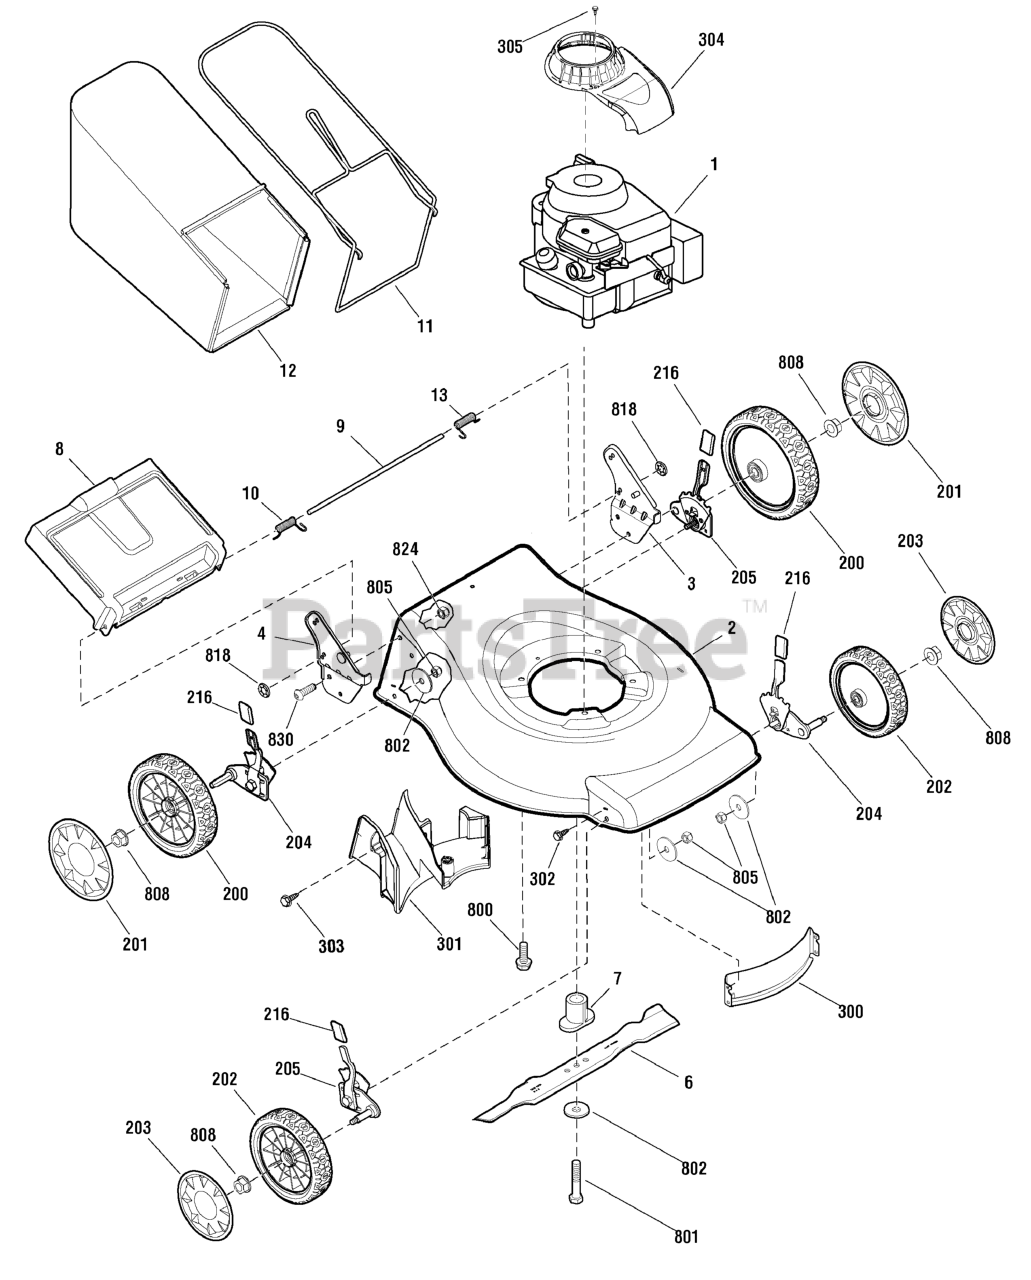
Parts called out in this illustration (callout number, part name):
1	* ENGINE, Briggs & Stratton 500 Series
2	MOWER HOUSING
3	BRACKET ASSEMBLY, Left Handle
4	BRACKET ASSEMBLY, Right Handle
6	BLADE, 19 Inch
7	BLADE ADAPTER ASSEMBLY
8	DOOR, Rear
9	ROD, Rear Door
10	SPRING, Torsion Rear Door, Right
11	FRAME ASSEMBLY
12	BAG ASSEMBLY
13	SPRING, Torsion Rear Door, Right
200	WHEEL, Rear
201	HUBCAP, Rear
202	WHEEL, Front
203	HUBCAP, Front
204	HEIGHT ADJUSTER ASSEMBLY, Left
205	HEIGHT ADJUSTER ASSEMBLY, Right
216	GRIP, Height Adjustment
300	BAFFLE, Front, 19
301	BAFFLE, Rear, 19
302	SCREW, Pan Head, Taptite, 1/4-20 x 1/2
303	SCREW, Pan Head, Taptite, 1/4-15 x 5/8
304	SHROUD
305	SCREW, Hex Washer Head
800	SCREW, Hex Head, 3/8-16 x 1
801	BOLT, Blade, 3/8-24 x 2
802	WASHER, Belleville
805	NUT, Nylock, M8 x 1-1/4
808	NUT, Flange, 3/8-16
818	PUSHNUT, 1/4
824	NUT, Flange, 5/16-18
830	SCREW , 5/16-18 x 3/4
1000	DECAL KIT
